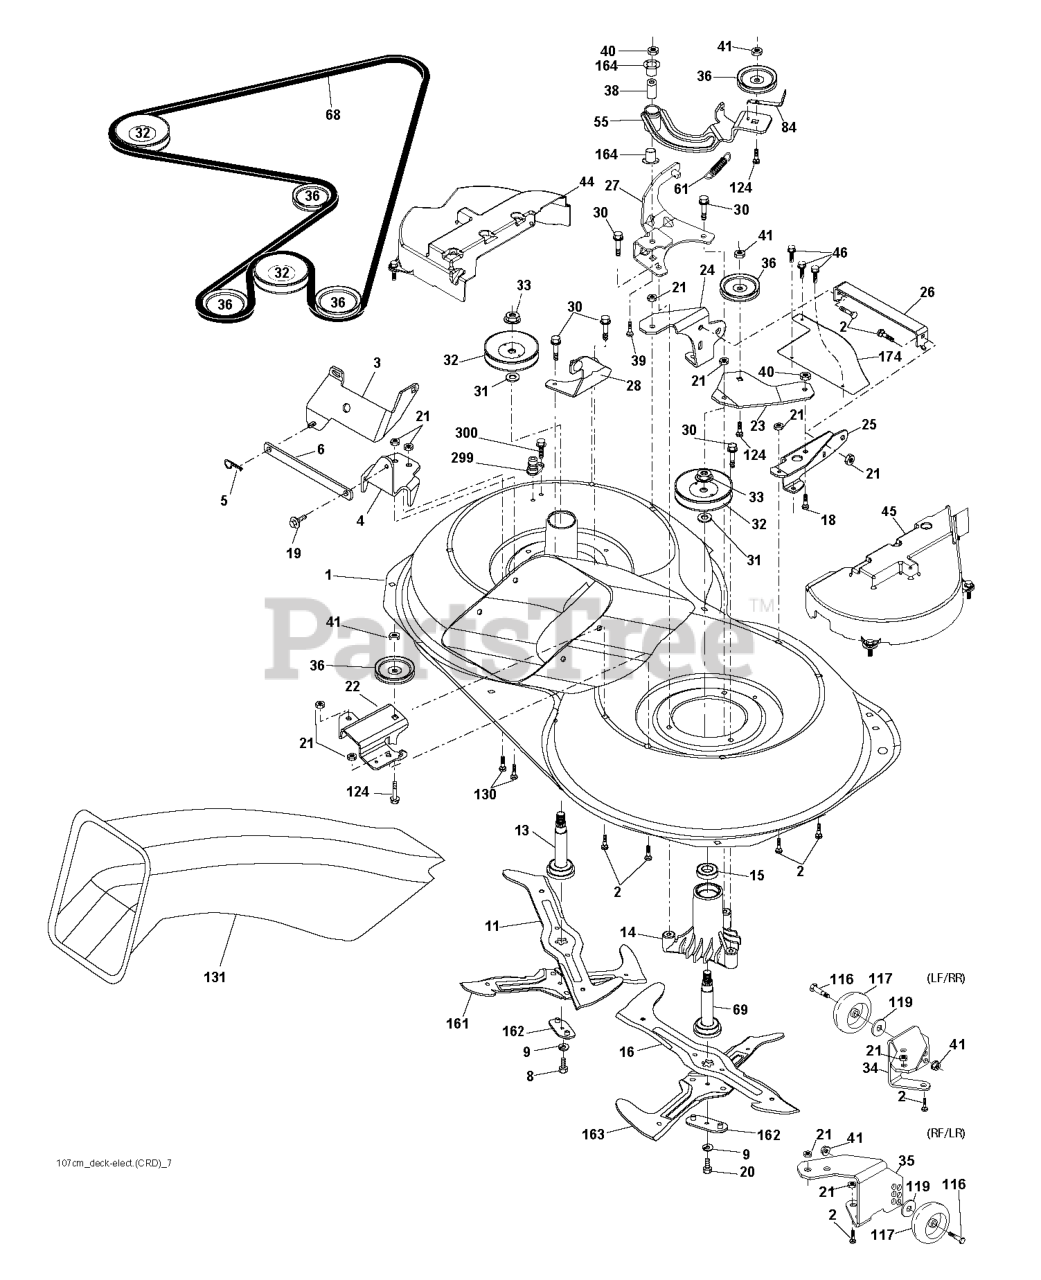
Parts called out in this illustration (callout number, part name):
1	Housing Asm. Mower 107 CRD
2	RP BOLT 5/16-18 X3/4 ZN/YEL GR
3	BRACKET.ASM.BAR.SWAY.CHASS
5	RETAINER-SPRNG RB
6	BAR.SWAY.92.CRD
8	BOLT.3/8-24X1.25 GR8
9	LOCKWASHER
11	BLADE.3N1.LH.CRD
13	SHAFT ASM VENT
14	HOUSING.MANDREL.VENTED (MACHD)
16	BLADE.3N1.RH.CRD
19	BOLT SHD 5/16-18
20	BOLT.3/8-24X1.25GR8. LHTHRD
21	LOCKNUT
22	BRACKET.IDLER.RR.107.CRD
24	BRACKET
25	BRACKET RF
26	SUPPORT
28	BRACKET
30	SCREW, WASHER HEAD
31	WASHER.SPACER.MANDREL
32	PULLEY.MANDREL.4.80 PD.2006
33	NUT.FLANGE.LOCK.TOP
34	BRACKET
35	BRACKET
36	PULLEY.IDLER.4.25
41	NUT LOCK FLG 3/8-16 UNC
44	COVER MANDREL LEFT
45	COVER MANDREL RIGHT
46	SCREW.1/4-20X5/8
55	ARM.IDLER.107.CRD
61	SPRING
68	HEX-BELT 107 MOWER
69	SHAFT.ASM.W/LWR.BRG.RH.THREAD
84	KEEPER, BELT IDLER
116	BOLT.SHOULDER.3/8-16X3-5/8.
117	RP WHEEL. GUAGE RALLY
119	WASHER
124	BOLT.3/8-16X1.50
130	BOLT.CARR.SQNK.5/16-18UNC.X3/4
131	CHUTE BAGGER
163	BLADE.CROSS.RH.CRD.107
164	BRNG T
174	PLATE
299	PORT.WASHOUT
300	SCREW.TT.#10-32X.5.3/8.FLANGE
